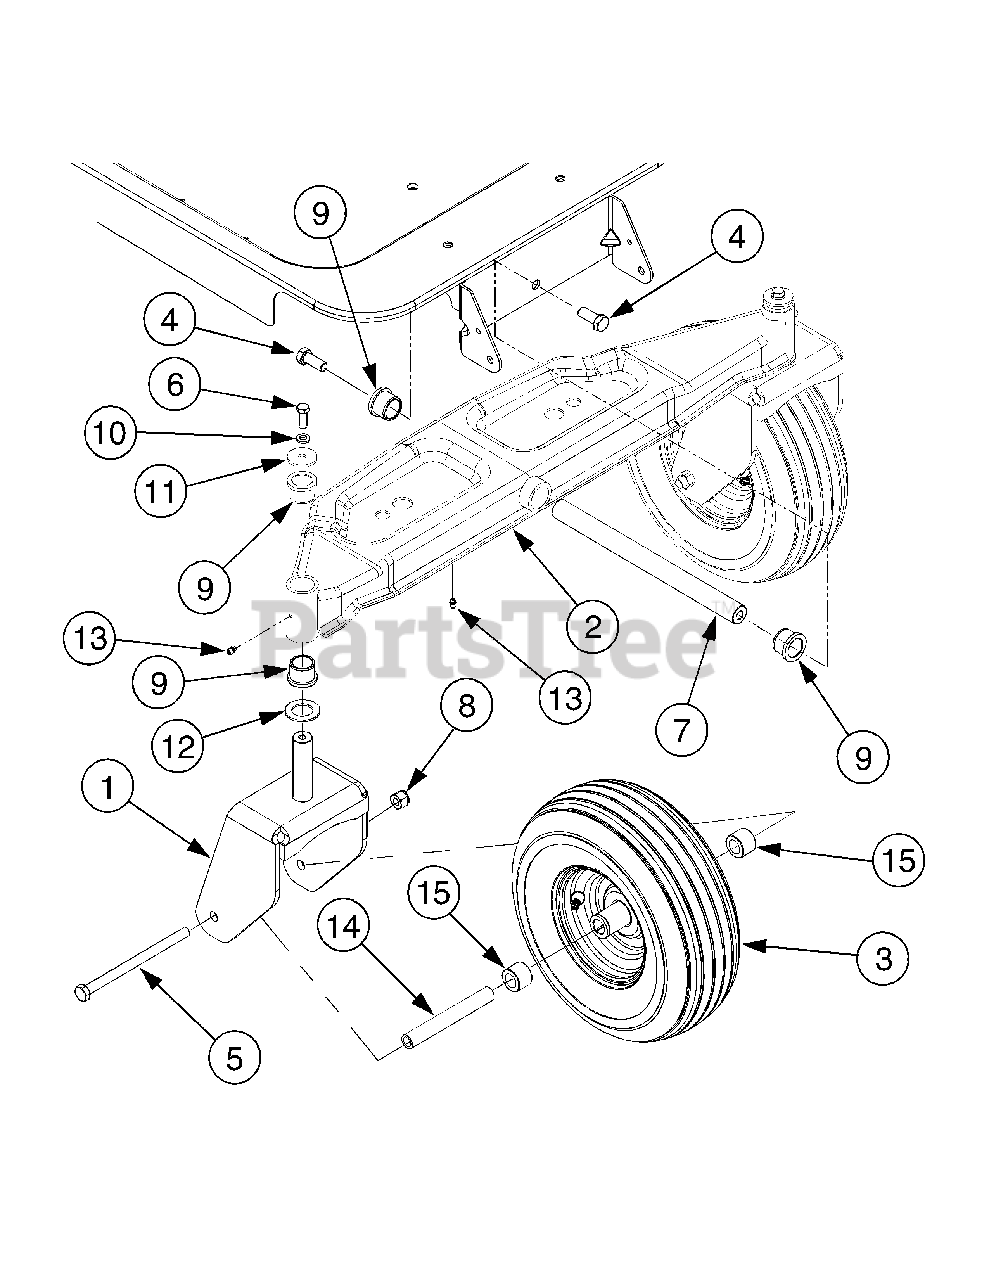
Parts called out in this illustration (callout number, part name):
1	Castor Wheel Bracket
2	Front Pivot Axle
3	Wheel Assembly, 13 x 5-6
4	Hex Lock Screw, 1/2-13 x 1.25
5	Hex Cap Screw, 1/2-20 x 7.25
6	Hex Cap Screw, 3/8-16 x 1.0
7	Axle Shaft
8	Hex Insert Lock Nut, 1/2-13
9	Flange Bearing, 1.0 x 1.246
10	Lock Washer, 3/8
11	Flat Washer, .39 x 1.5 x .134
12	Flat Washer, 1.0 x 1.75 x .10
13	Lube Fitting, 3/16 Drive
14	Spacer, .51 x .75 x 5.825
15	Hub, .76 x 1.23 x .92
